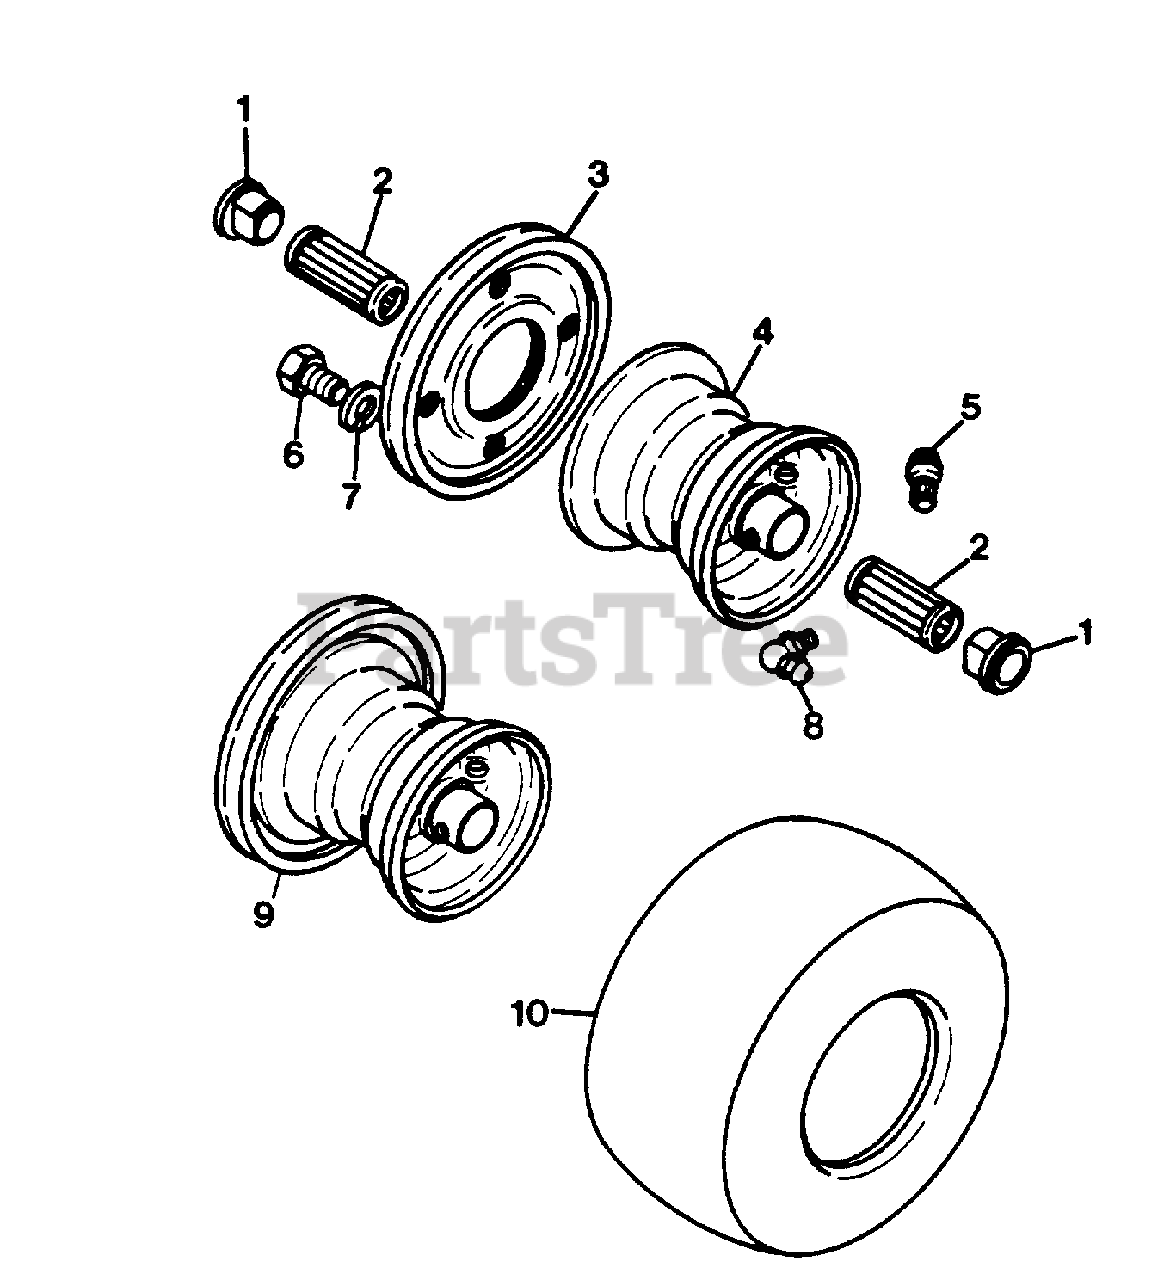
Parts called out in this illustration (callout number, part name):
1	BEARING, FLANGE
2	BEARING, 7/8X2.50
2	BEARING, 7/8X2.00 (PRO 32)
3	ASSEMBLY, PULLEY AND BRAKE DRUM
4	ASSEMBLY, WHEEL
5	ASSEMBLY, VALVE STEM
6	BOLT, HEX 5/16-18X.75
7	WASHER, LOCK 5/16 REG.
8	FITTING, LUBE 90 DEG.
9	RIM (PRO-32)
10	TIRE, 13X6.50-6
10	TIRE, 13X5.00-6 (PRO-32)
NS	ASM., WHEEL 13X5.00-6 (PRO-32)
